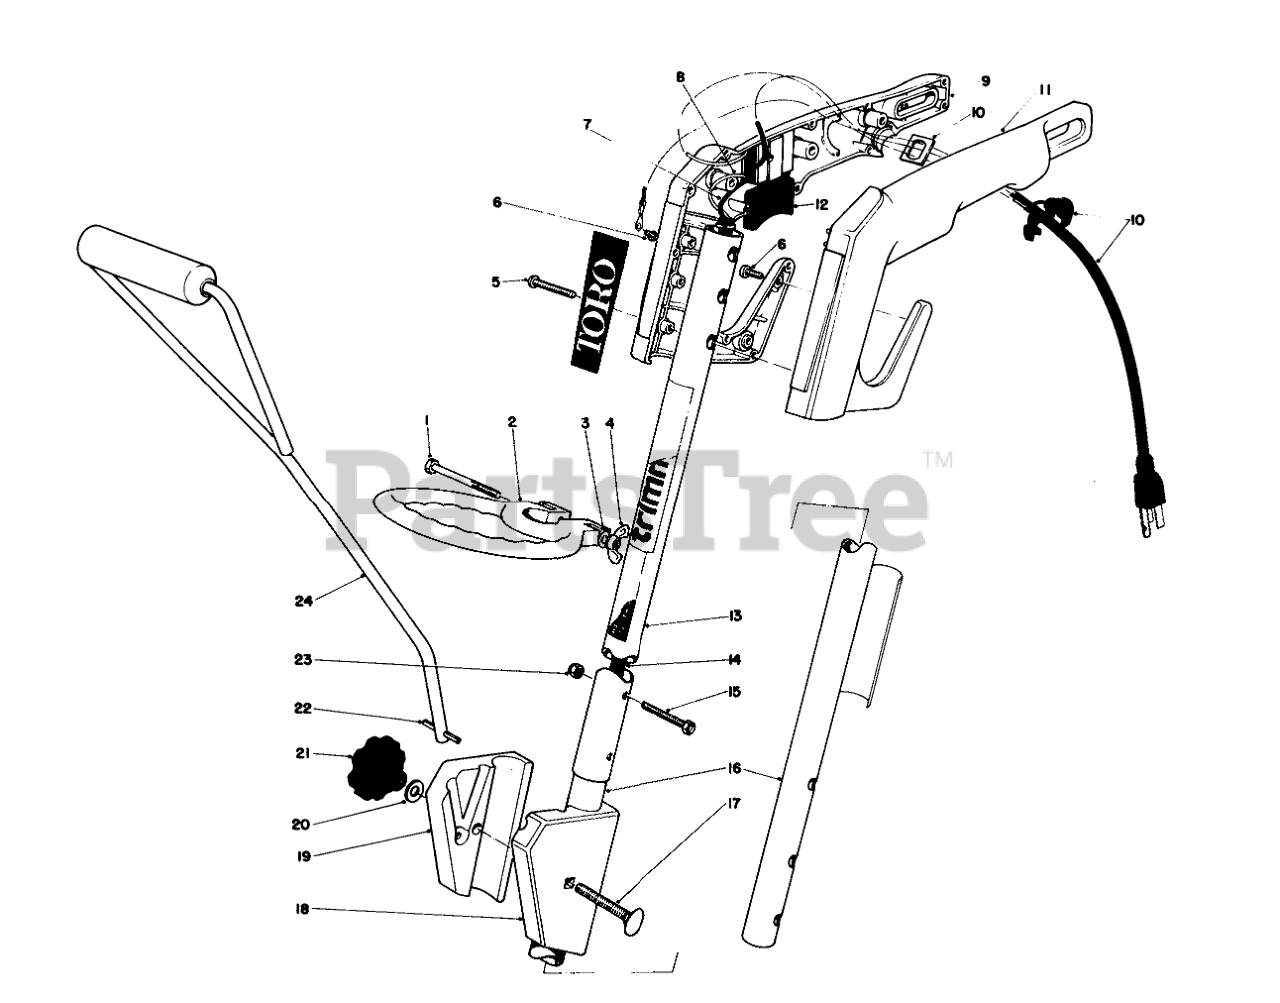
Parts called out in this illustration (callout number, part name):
1	SCREW-HH
3	WASHER-FLAT
4	NUT-WING SPECL
15	Screw
17	SCREW-CARR
20	WASHER-PLAIN
22	PIN-ROLL, SLOT
23	NUT-LOCK, NI
